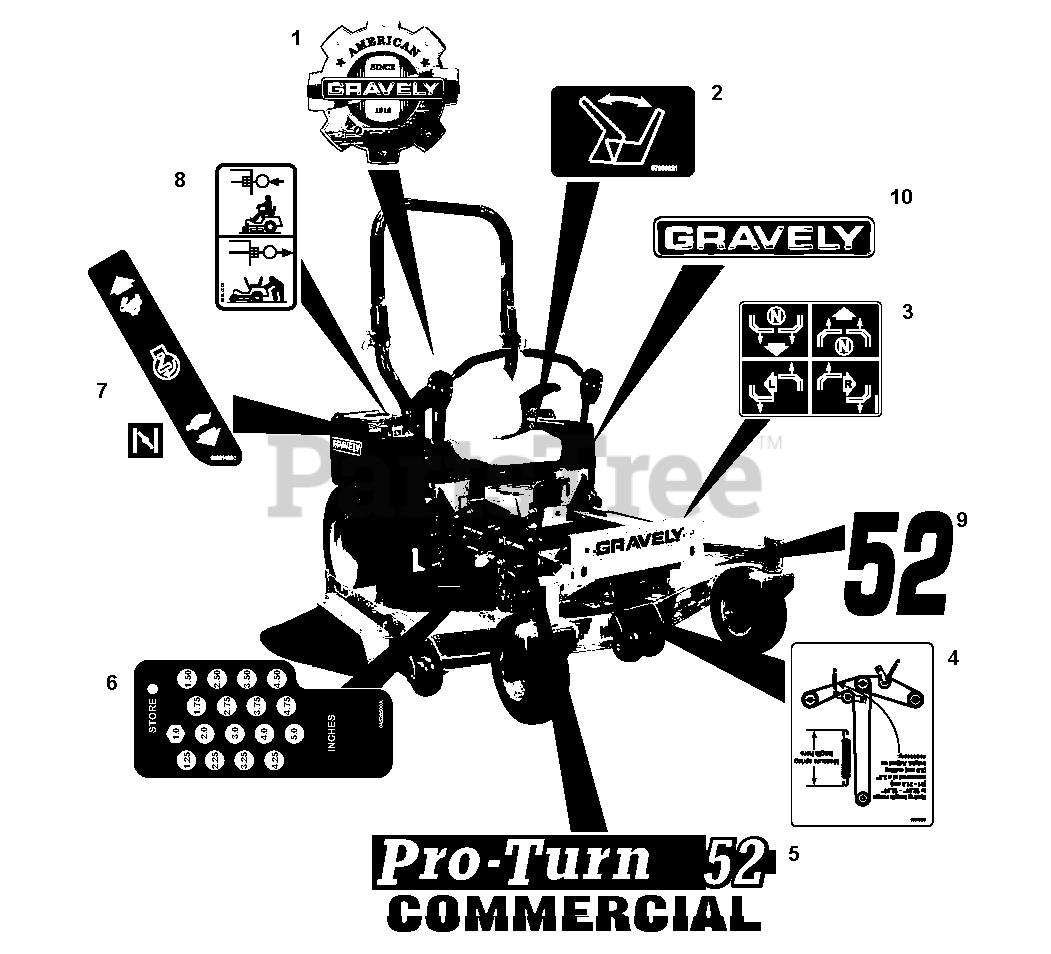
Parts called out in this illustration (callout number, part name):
1	Decal, Gravely Heritage, Large
2	Decal, Seat Release
3	Decal, Instructional- Steering
4	Decal, Belt Routing
5	Decal, Pro-Turn 48 (992200, 204)
5	Decal, Pro-Turn 52 (992201, 205)
5	Decal, Pro-Turn 60 (992202, 203, 206)
6	Decal, Height of Cut
7	Decal, Control
8	Decal, Transmission Disconnect
9	Decal, 48" (992200, 204)
9	Decal, 52" (992201, 205)
9	Decal, 60" (992202, 203, 206)
10	Decal, Fuel Tank, Gravely
